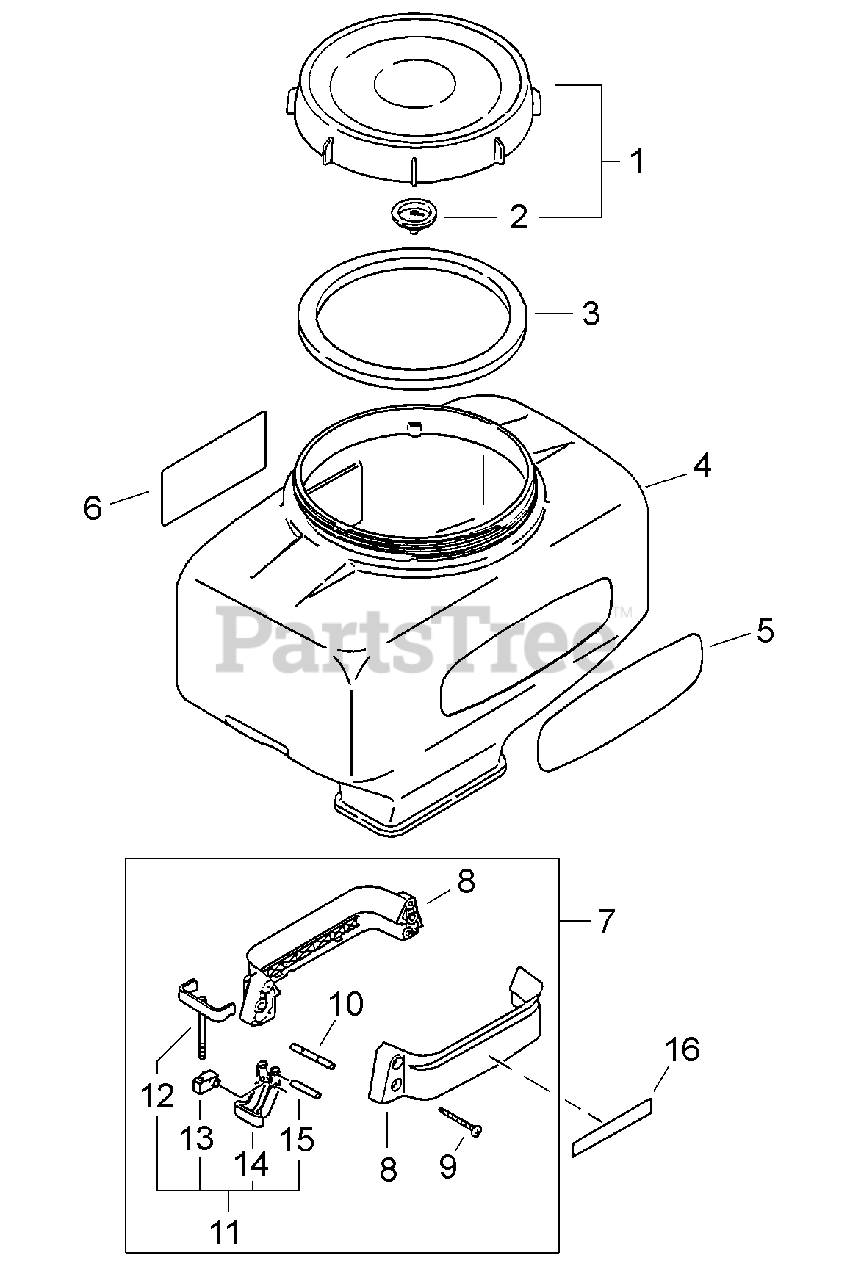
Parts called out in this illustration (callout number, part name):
1	CAP ASSY, CHEMICAL TANK
2	CONNECTOR, PIPE
3	GASKET, CAP
4	TANK, CHEMICAL 23L
5	LABEL, ECHO
6	LABEL, CAUTION - ISO
7	BRACKET ASSY, CHEMICAL TANK
8	BRACKET, CHEMICAL TANK
9	SCREW, TAPPING HS M5×35
10	PIN, LOCATING
11	RETAINER ASSY, CHEMICAL TANK
13	CONNECTOR, BRACKET
14	RETAINER, CHEMICAL TANK
15	PIN 7×37
16	LABEL, DM-6110
